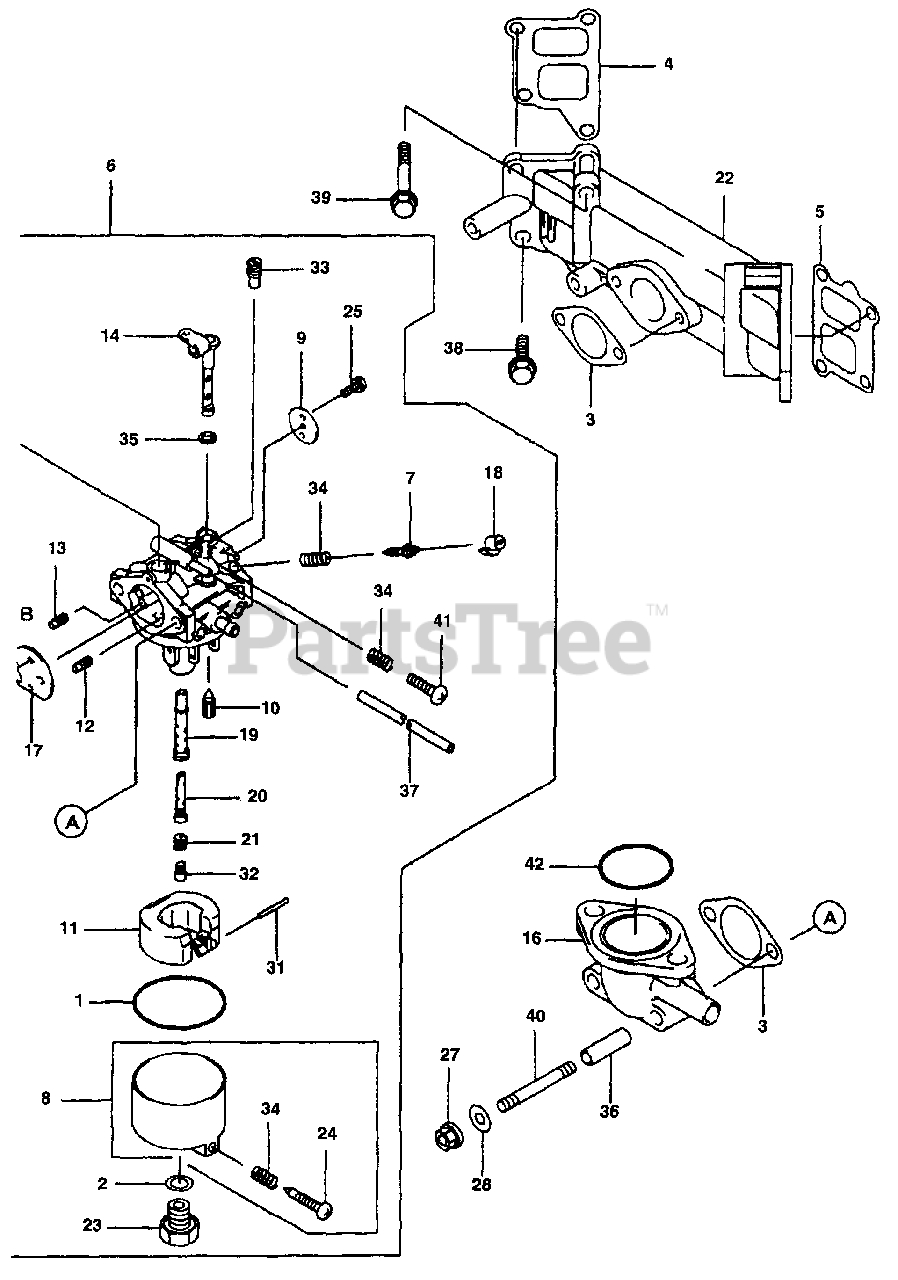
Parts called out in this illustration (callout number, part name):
3	Intake Pipe Gasket
6	Carburetor Ass'y
7	Pilot Air Screw
8	Float Chamber
9	Throttle Valve #130
14	Carb. Shaft Throttle
19	Main Nozzle #18A
20	Main Nozzle #18A
21	Main Jet Holder
22	Intake Manifold
27	Nut
28	Washer, 6.2 x 15 x 1.2
32	Main Jet #112.5
33	Pilot Jet #38.8
38	Flanged Bolt
39	Flanged Bolt
